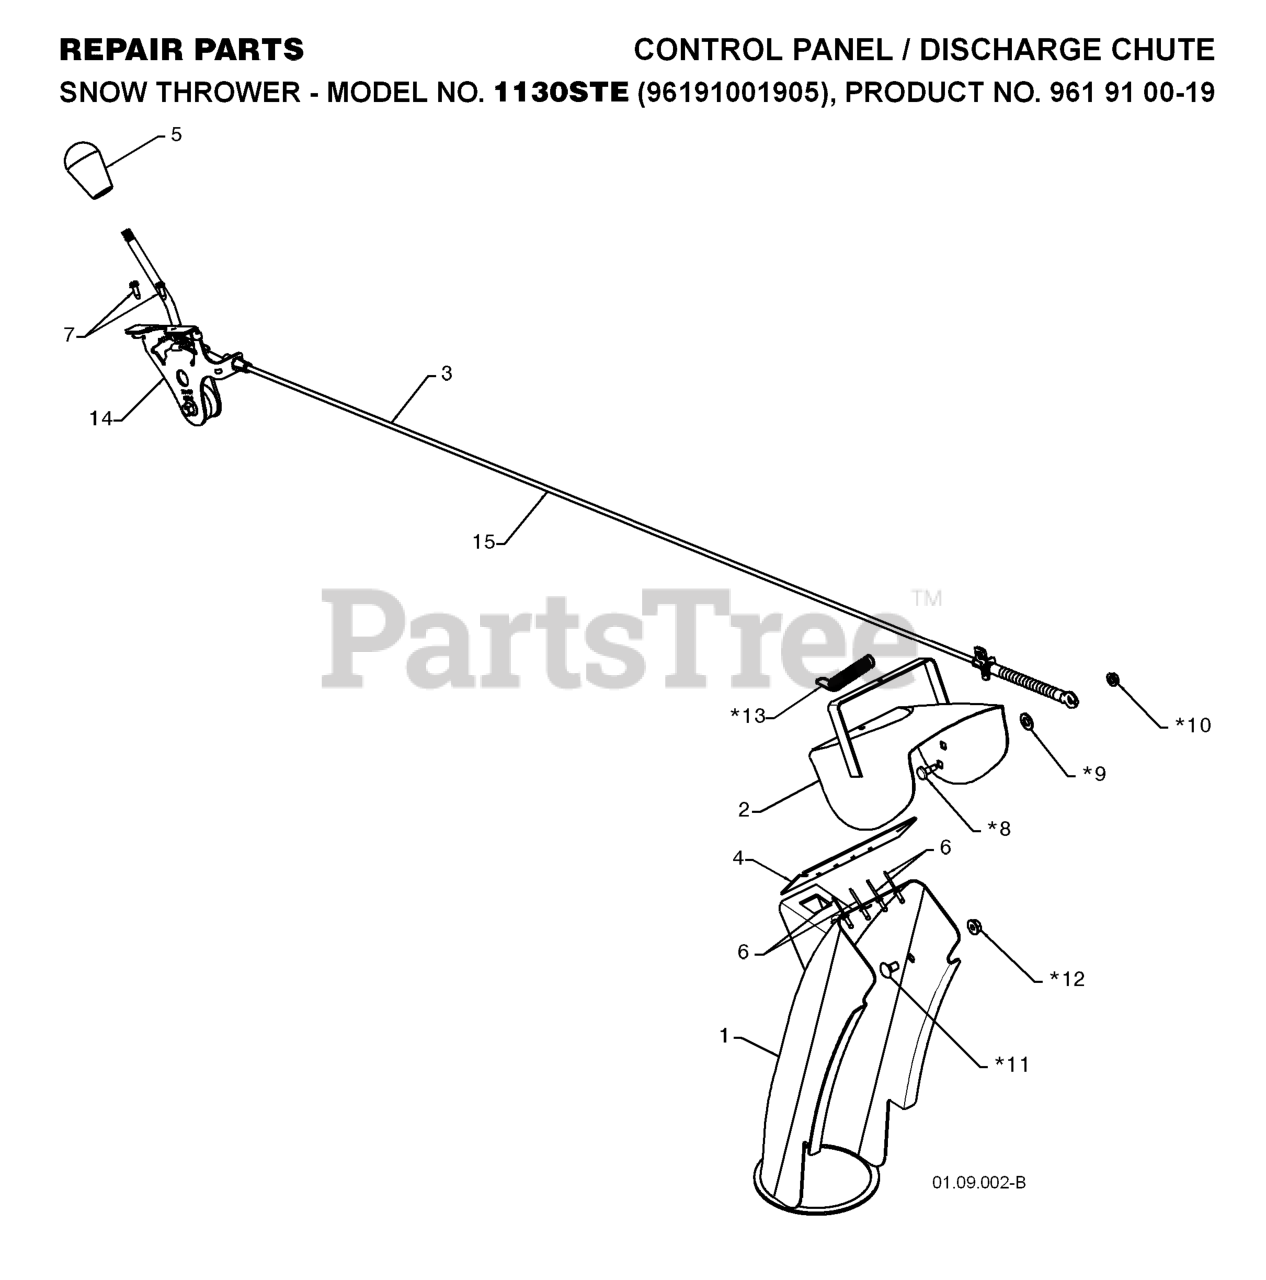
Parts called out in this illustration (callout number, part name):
1	CHUTE ASSEMBLY
2	DEFLECTOR.WELDMENT.PNT.ORANGE
3	RP.CONTROL.ASM.DEFLECTOR.SNOW
4	SEAL.DEFLECTOR
5	KNOB LEVER, BLACK
6	RIVET BLIND
7	SCREW #10-24 X 5/8
14	RP CNTRL.HEAD.ASSEM.DEFLECTOR
15	RB SERVICE.CHUTE.DEF.CBL.BLK
